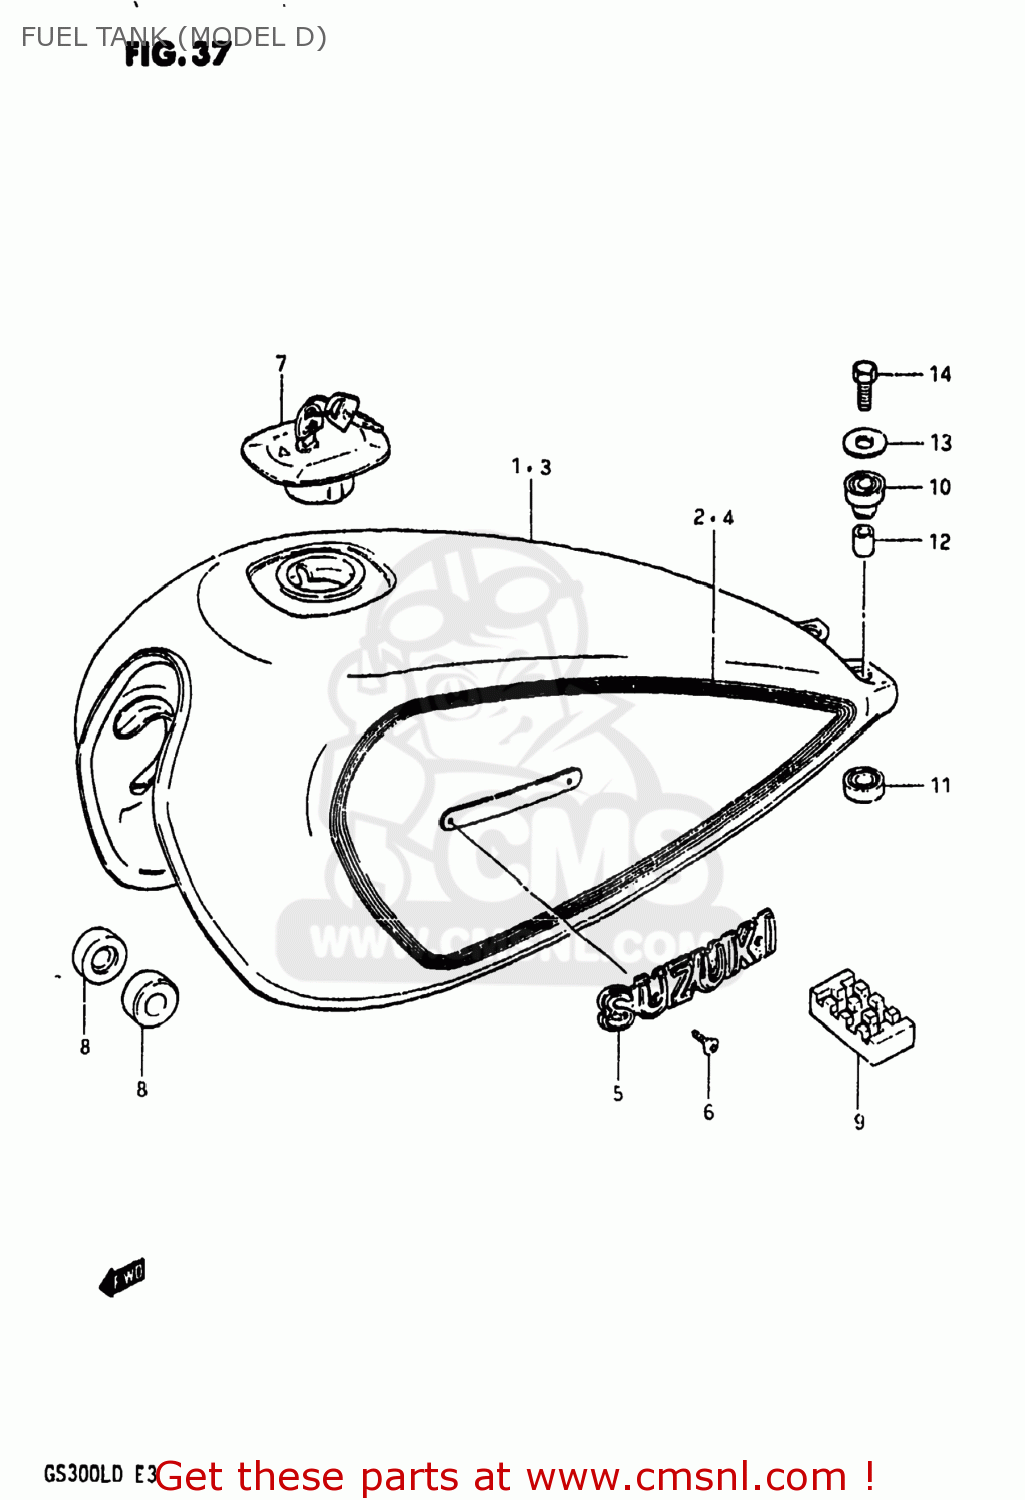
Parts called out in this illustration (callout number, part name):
1	TANK ASSEMBLY,FUEL
2	TAPE SET,FUEL TANK
3	TANK ASSEMBLY,FUEL
4	TAPE SET,FUEL TANK
5	EMBLEM,FUEL TANK
6	SCREW 3X6
7	CAP SET,FUEL TANK
8	CUSHION
9	CUSHION
10	CUSHION
11	CUSHION
12	SPACER
13	WASHER (6.5X24X1.6)
14	BOLT
